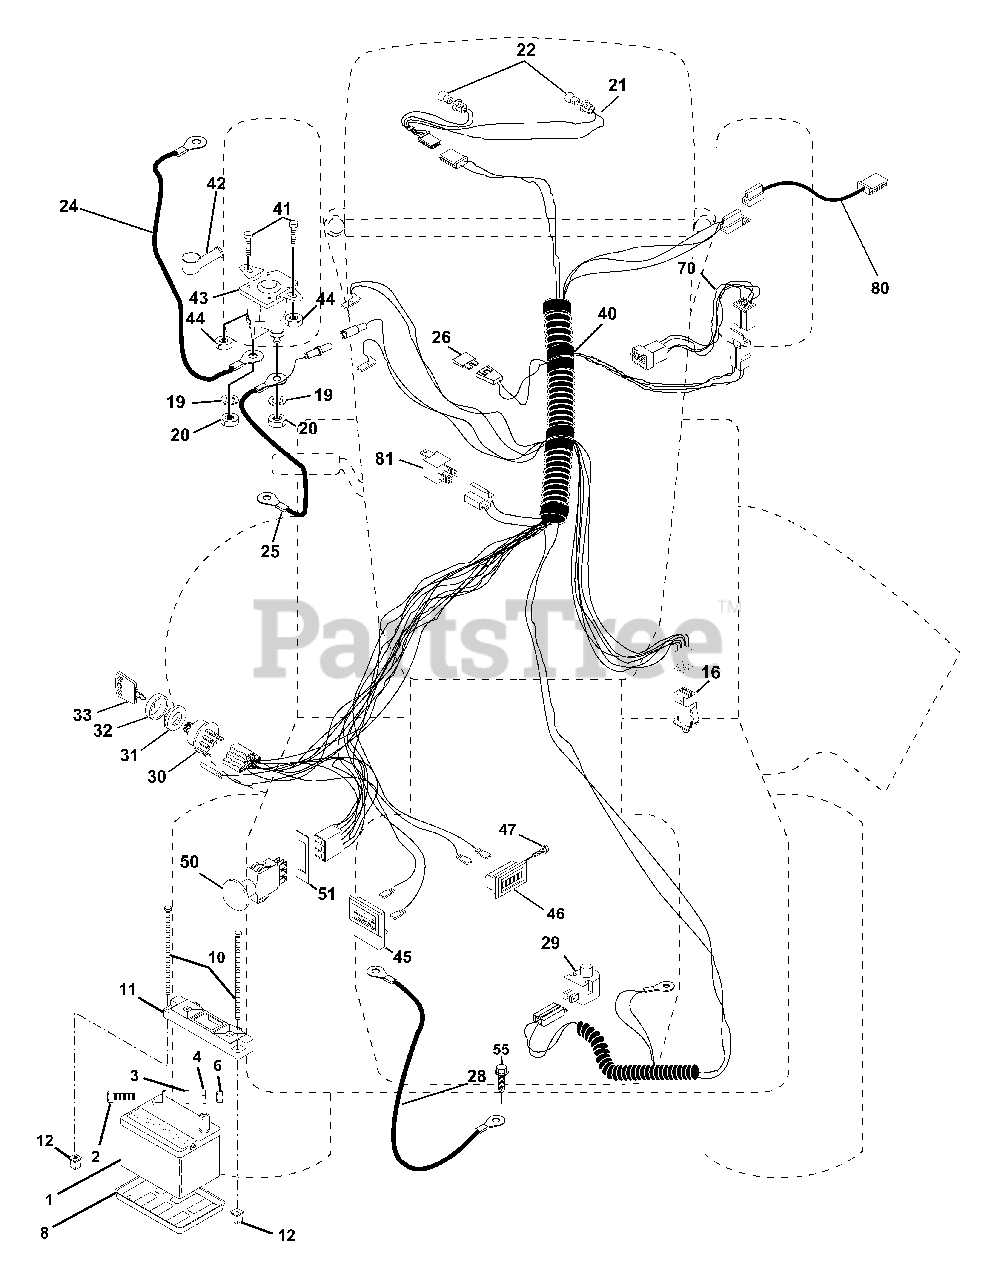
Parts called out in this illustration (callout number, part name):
1	Battery 12 Volt 25 AMP
2	Bolt Hex Hd 1/4-20unc X 3/4
3	Washer 9/32 X 5/8 X 16 Ga.
4	Washer Lock Hvy Helical 1/4
6	Nut Fin Hex 1/4-20 Unc
8	Tray Battery 7.80 x 5.25 Blk
10	Bolt Btr Frt 1/2-20 x 7.5 Zinc
11	Holddown Battery Front Mount
12	Nut Push Nylon 1/4" Battery Frt
16	Switch Interlock Push-In
19	Washer Lock 1/4
20	Nut Jam Hex 1/4-20 Unc
21	Harness Asm Light W/4152j
22	Bulb Light #1156
24	Cable Battery 6 Ga 11" red
25	Cable Battery 6 Ga 44" red w/16 wire
26	Fuse 30 AMP Auto Green
28	Cable Ground 6 Ga 21" black
29	Switch Plunger Normal Op Olive
30	Switch Ign 4 pos w/lights
31	Nut Ignition
32	Cover Sw Ignition
33	Key Ign Modelled Generic
40	Harness Ign.
41	Bolt Blk Fin Hex 1/4 - 20 x 1/2
42	Cover Terminal Red
43	Solenoid
44	Nut Keps Hex 1/4-20 Unc
45	Ammeter Rectangular 6 Amp
46	Meter Hour
47	Screw 10-24 x 1/2 Black
50	Switch PTO 3PDT Black Delta 96
51	Ring Retainer PTO
55	Screw Thdrol 5/16-18 x 1/2 Tyt
70	Harness, Eng Kohl Cmd-L Dual
80	Harness Clutch Evx
81	Relay Asm.
